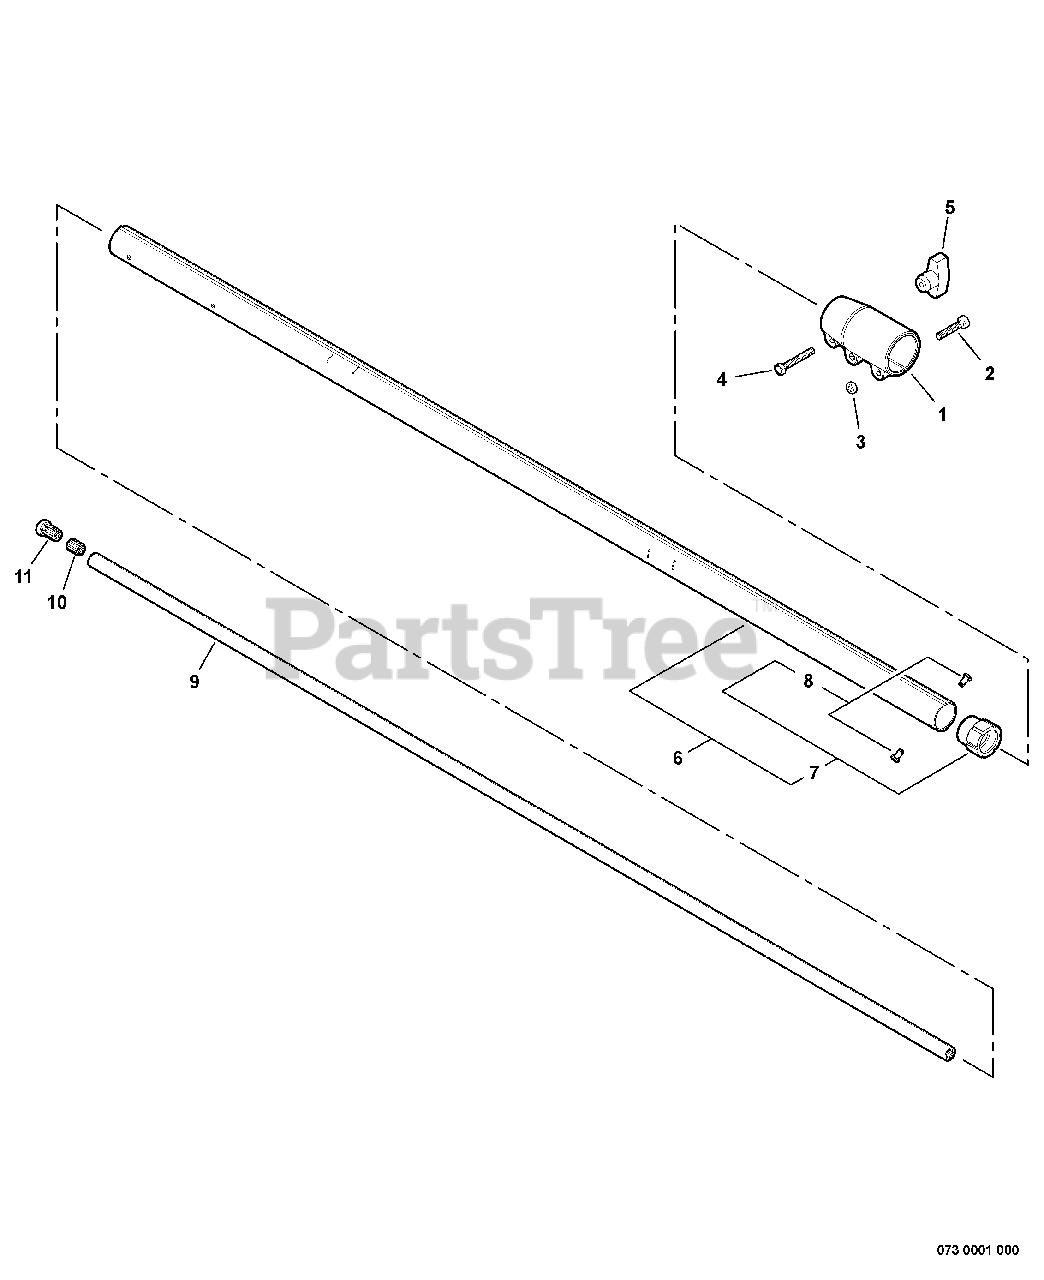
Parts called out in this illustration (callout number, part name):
1	COUPLING
2	SCREW - 5X20
4	BOLT - 6X25
5	THUMBSCREW
6	MAIN PIPE ASSY - BLACK
7	BEARING HOLDER ASSY
9	DRIVESHAFT - UPPER
10	SOCKET - INNER
11	SOCKET - OUTER
